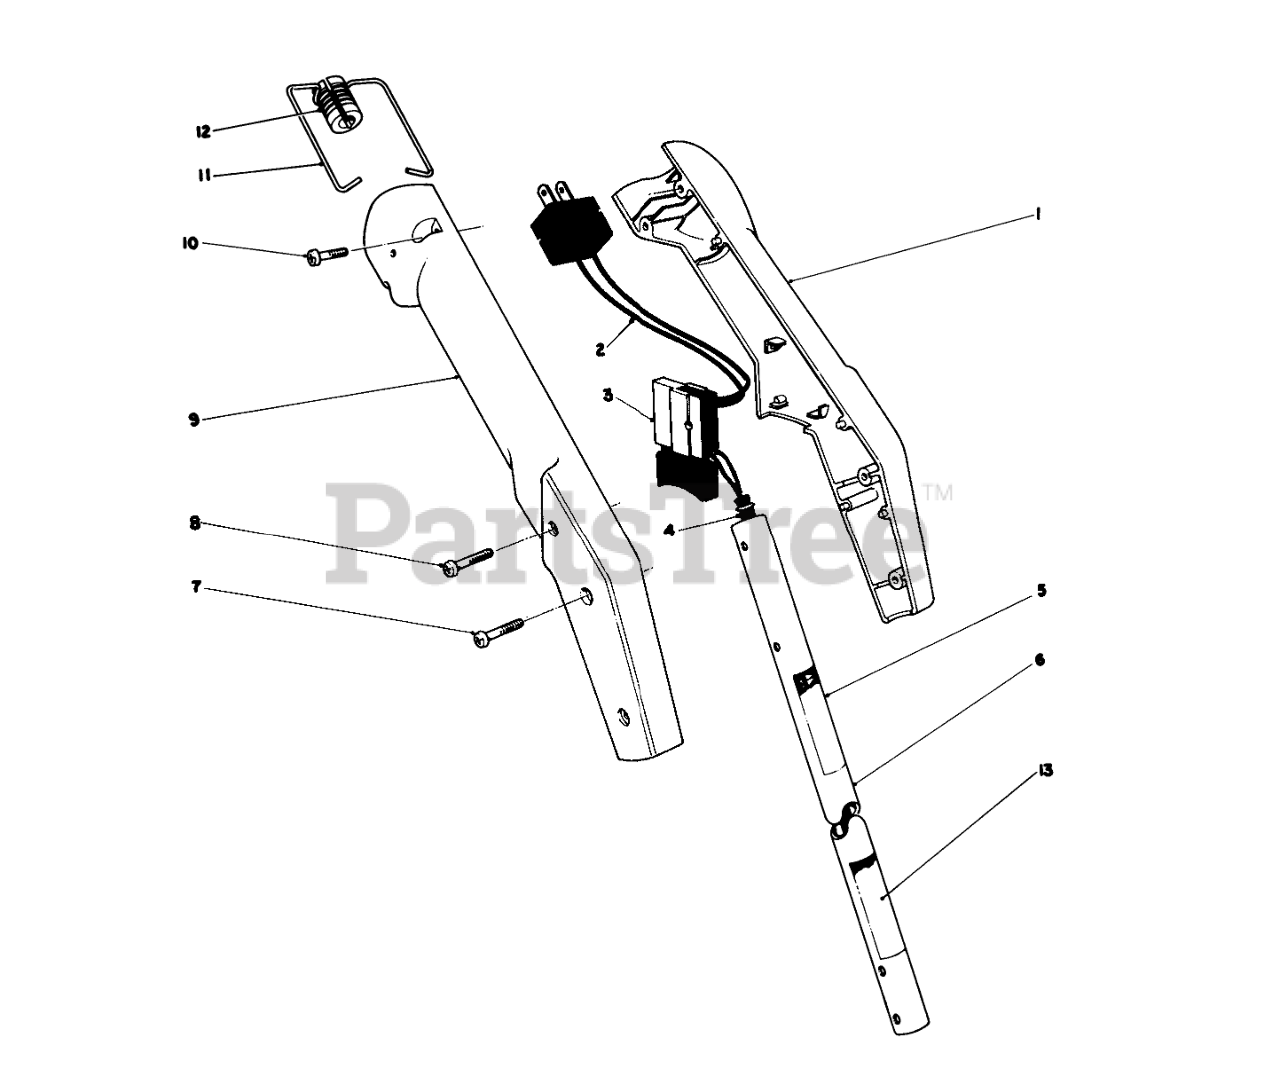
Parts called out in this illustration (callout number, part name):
1	Left Hand Grip
2	WIRING HARNESS UPPER
3	SWITCH SINGLE SPEED
4	Main Wiring Harness
5	Caution Decal
7	Screw
9	Right Hand Grip
10	SCREW-PPH
11	Extension Cord Wire Clamp
12	RETAINER EXT. LORD
13	REPLACEMNT SERIAL PLT
